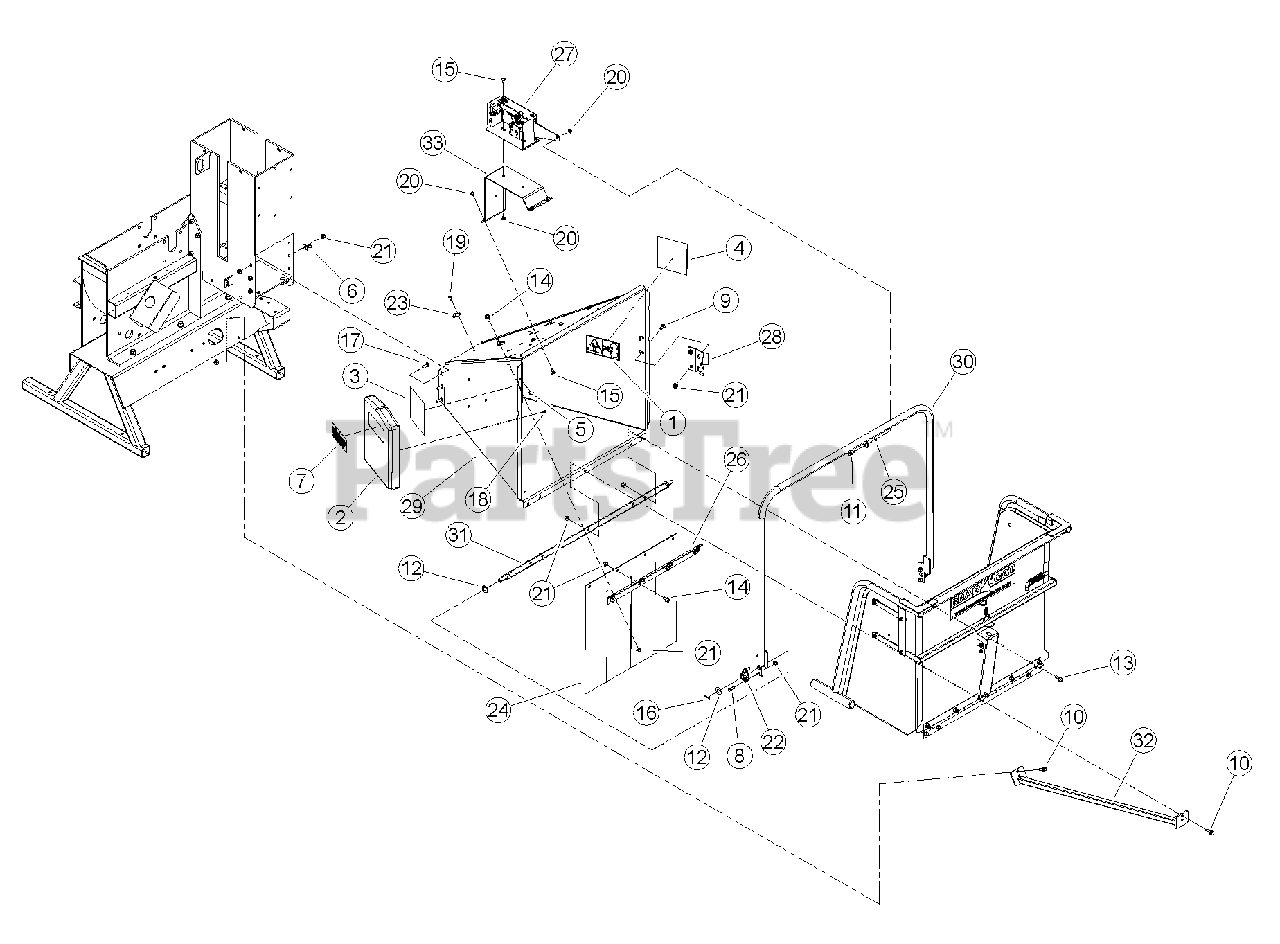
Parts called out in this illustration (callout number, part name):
1	DECAL, BLADE DANGER ISO
2	CONTAINER, INSTR. MANUAL
3	DECAL, FEED POSITION
4	DECAL, FEED POSITION
5	BUMPER, RUBBER
6	CLAMP, 9/16 COATED
7	DECAL, MUTILINGUAL MANUAL
8	BOLT, 3/8 X 1 HEX HD GR5 ZP
9	BOLT, 3/8 X 1" GR5 CRG NC ZP
10	BOLT, 3/8 X 1-1/4 FLANGE NC
11	BOLT, 5/16 X 1 FLANGE NC
12	WASHER, 5/8" SAE FLAT ZP
13	BOLT, 3/8 X 1 FLANGE NC
14	BOLT, 3/8 X 3/4 FLANGE NC
15	BOLT, 5/16 X 3/4 GR5 CRG NC ZP
16	PIN, 1/8 X 1.00 ZP COTTER
17	BOLT, 3/8 X 1-1/4" GR5 CRG NC ZP
18	RIVET, AL BLIND 1/4 X 1/2 DOME HEAD
19	RIVET, AL BLIND 1/4 X 3/4 DOME HEAD
20	NUT, 5/16-18 NYLOCK-FLANGE
21	NUT, 3/8-16 NYLOCK FLANGE
22	BEARING, SIDE FLANGE MOUNT 5/8"
23	CLAMP, CABLE MOUNT
24	FLAP, 9 INCH CHUTE
25	SPACER, IDLER PIVOT
26	SUPPORT, 9 INCH CHIPPER FLAP
27	ASSEMBLY, "CE" SWITCH BOX
28	PLATE, TRAY STOP
29	WELDMENT, BIG CHIPPER CHUTE
30	WELDMENT, CONTROL ARM
31	WELDMENT, CONTROL PIVOT
32	WELDMENT, CHUTE SUPPORT
33	MOUNT, SWITCH BOX
